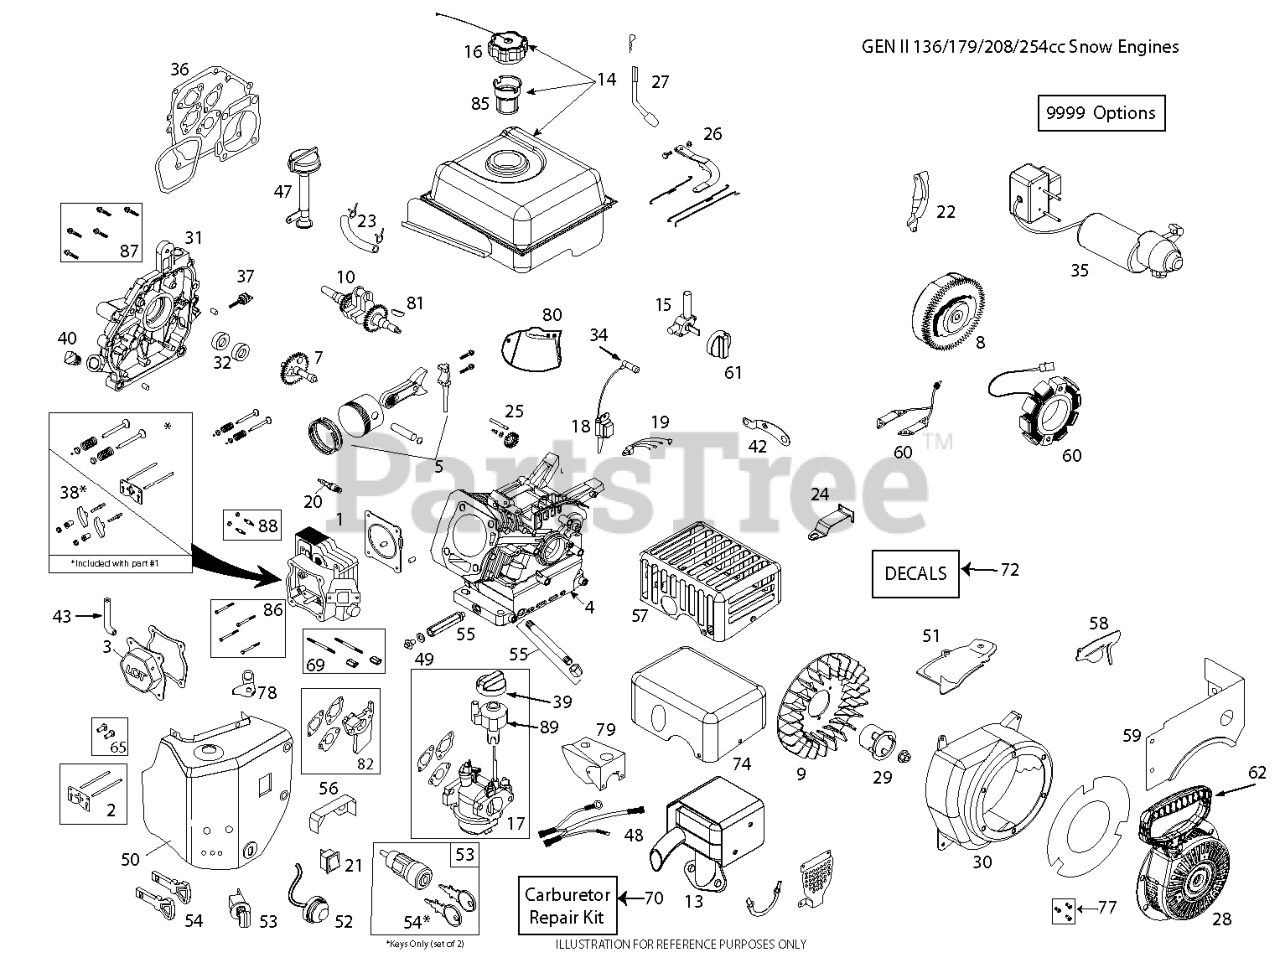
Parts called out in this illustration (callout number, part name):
1	CYLINDR.HEAD.SRV.KIT W/GASKET
2	KIT.PUSH.ROD.SRV(SK208-1001)
3	VALVE COVER ASSEMBLY
4	CYLINDER LCT.208 GEN II SNO
5	KIT.PISTON.SRV(SK208-1400)
7	KIT.CAMSHAFT.208CC.LCT
8	208CC ELEC START FLYWHEEL
9	FLYWHEEL FAN 420586
10	CRNKSHFT-KYD#14.208CCSKSNO8001
13	MUFFLER ASSY LCT GENII SNO
14	FUEL.TK.ASSY.GENII.SKSN0311.1
15	FUEL.PETCOCK.SNOW(SKSN4900)
16	FUEL CAP OVERSIZED CLICK STYLE
17	CARBURETTOR L10-1D.W/SP
18	COIL.ING.CDI.HI TEMP.SKSNO416.
20	SPARK.PLUG(2083810)
21	SWITCH.ON/OFF(SKSN-0403)
22	SHLD.ELEC.START.FLY(SKSN-0605)
23	FUEL HOSE KIT
24	SPEED.CTRL.BRKT.(SKSN0150)
25	GOVENOR.GEARS ASM(SK2082900)
26	CARBURETTOR GOVERNOR LINK.ASM.
27	KIT.GOVERNOR.CRANK(SK208-3100)
28	RECOIL.STRT.ROUND(BLK) SNOW
29	STRTER.CUP(NON-SLOT)SKSN0601.2
30	BLOWER HSG.LCT.208.ES W/OIL
31	CRANKCASE COVER.PRESS-N TYPE
32	SEAL KIT (2 PCS)
34	SPARK.PLUG.BOOT.SNW,SKSN4691.1
35	ELEC.START.GEN2.SKSN0451.1
36	GASKET.KIT.208CC(SK2084300.1)
37	DIPSTICK SMALL
38	ROCKER ARM KIT
39	CHOKE.KNOW.SNOW(SKSN4500)
40	NON REMOVABLE PLUG
42	CDI.BOX.BRACKET SNOW
43	TUBE.BREATHER.LCT.208
47	HIGH OIL FILL DIPSTICK ASSEM
48	WIRE.HARNESS.SNOW
49	KIT.OIL.DRAIN.PLUG(SK2089911
50	HEATER.BOX.ASY-GEN2
52	PRIMER.BULB.WITH HOSE (SNOW)
53	SWITH.KEY.ASSEM.SNOW.SINGLE.ST
54	KEY SET(2 KEYS) SKSN0407.1
55	OIL PIPE DRAIN EXTENDED.LCT SK
56	SHIELD.VAPOR.SNOW
57	SHIELD.MUFFLER.CE.COMPLIANT
58	GOVERNOR.LINK.SHIELD PLATE
59	FUEL.TNK.SKRT.GENII.SKSN0103.1
60	208CC 60W ALTERNATOR
61	FUEL KNOB-SNOW
62	HANDLE.RECOIL.DELUXE.LCT
65	TAPPET.KIT.LCT.208CC
69	CARB.STUDS & COUPLING KIT.SNOW
70	CARB.REPAIR.KIT.LCT.SK9900.2
74	HEAT SHIELD MUFFLE
77	BOLT.KIT.RECOIL.LCT.ALL.ENGINE
79	COVER.CARBURETOR.SNOW
81	KEYS.FLYWHEEL.208/414CC.5PACK
82	SPACER.CARBURETOR.208CC.LCT
85	STRAINER.FUEL.TANK.LCT.208CC
86	KIT.BOLT.CYLINDER.HEAD.(4PC)
87	KIT.BOLT.CRANKCASE.COVER.6PC
88	STUD.MUFFLER.KIT.LCT
9999	HIGH.ALTITUDE.JET 6,000FT
